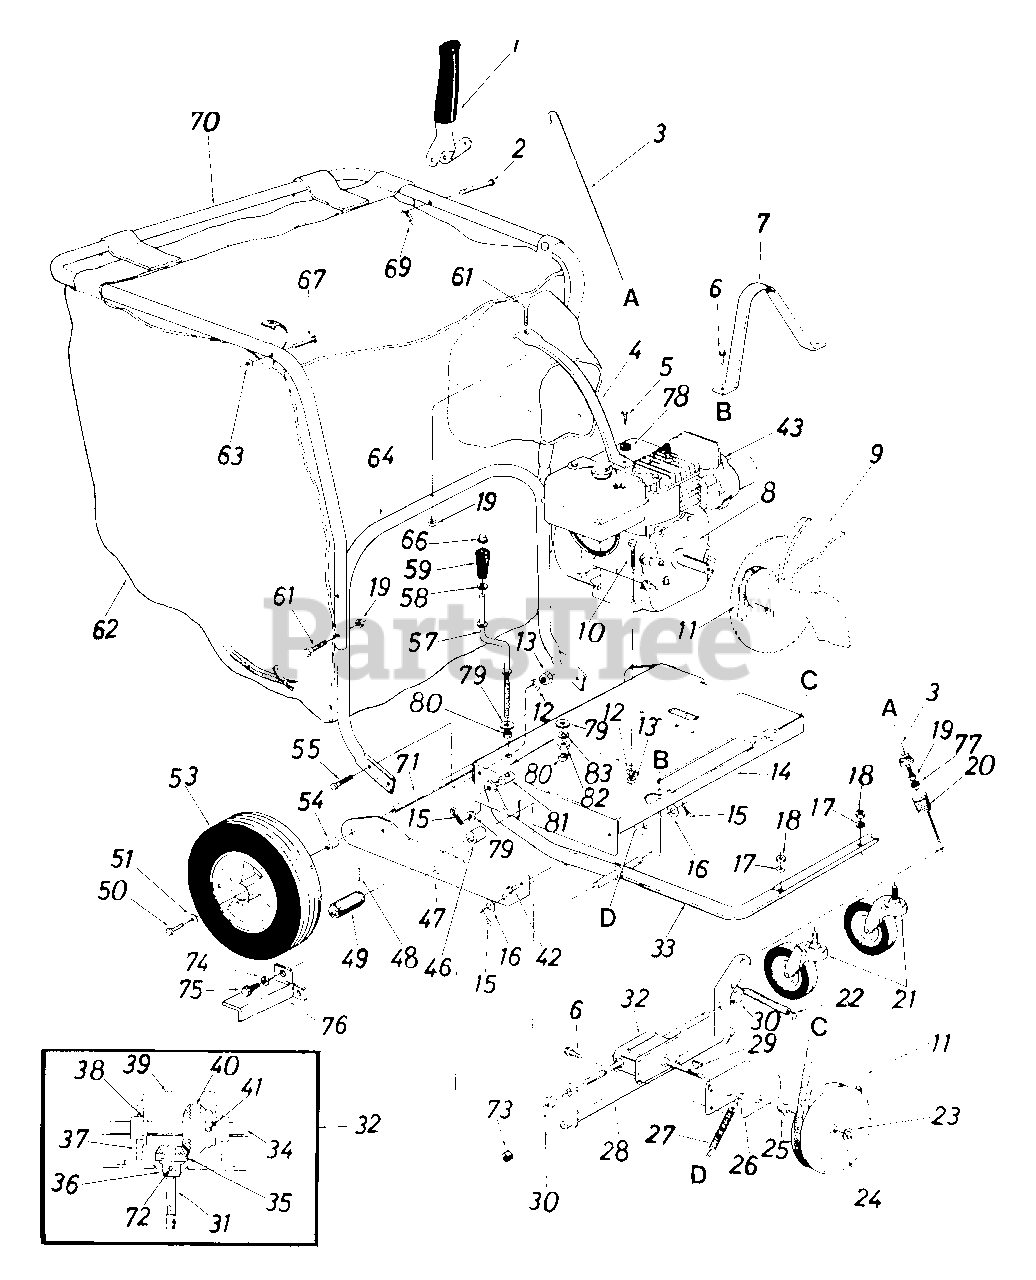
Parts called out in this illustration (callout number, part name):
1	Clutch Grip Ass'y.
2	Clevis Pin .375" Dia. x 1.88"
3	Clutch Rod 32" Lg.
4	Handle Brace (Painted)
5	Part of Engine
6	Hex Wash. Hd. AB-Tap Scr. 1/4" x .62" Lg.
9	Air Vane Plate Ass'y. (675 and 677)
11	"V"-Belts
12	L-Wash. 5/16" I.D.
13	Hex Nut 5/16-18 Thd.
16	Fl-Wash. .63" I.D. x 1.25" O.D.
17	L-Wash. 1/2" I.D.
18	Hex Nut 1/2-13 Thd.
19	Hex Cent. L-Nut 1/4-20 Thd.
20	Extension Spring .78" O.D. x .75" Lg.
21	Swivel Caster Wheel 5" Dia. x 1.25"
22	Extension Spring .38" O.D. x 7.50" Lg.
23	Snap "E"-Ring .50" Dia. Shaft
24	"V"-Pulley 5/8" x 6.50" O.D.
25	Flange Bearing .502" I.D.
28	Clutch Bracket Ass'y.
29	#2 Woodruff Key 3/32" Dia. x .81" Lg.
30	Hex Flange Bearing Bronze .625" I.D.
31	Pinion Shaft .50" Dia. x 5"
32	Gear Box Ass'y. Comp.
35	Bevel Gear .50" I.D. x 14 Teeth
36	Flange Bearing .503" I.D.
37	Gear Box
38	Flange Bearing .630" I.D.
39	Gear Box Cover
40	Bevel Gear .62" I.D. x 28 Teeth
41	Spring Pin Spiral 3/16" Dia. x 1.25" Lg.
42	Hex Wash. Hd. AB-Tap Scr. 5/16" x .75" Lg.
43	Engine
46	Spacer .63" I.D. x .88" 0 D. x 56" Lg
49	Drive Pinion
50	Hex Locking Bolt 5/16-24 x .62" Lg.
51	Fl-Wash. .34" I.D. x.87" O.D.
53	Wheel Ass'y. Comp. 12" x 3"
54	Spacer .63" I.D. x 1.0" 0 D. x .94" Lg.
55	Hex Bolt 5/16-18 x .75" Lg.
57	Height Adjustment Crank
58	Fl-Wash. .385" I.D. x .62" O.D.
59	Crank Knob
61	Hex Bolt 1/4-20 x 1.75" Lg.
62	Vacuum Bag - Felt
63	Push Speed Nut .25" Dia. Stud
66	Push Nut 3/8" Dia.
67	Stud Pin .250" Dia. x 1.75"
69	Internal Cotter Pin 3/8" Dia.
70	Upper Handle (Painted)
71	Rear Axle
72	Spring Roll Pin 5/32" Dia. x 1.121
73	Spacer .82" I.D. x 1.0" 0 D. x .305 Lg
74	L-Wash . .265" I.D.
75	Hex Self-Tap Scr. 1/4" x 3/8" Lg
78	Belleville Washer
79	Fl-Wash. .35" I.D. x.87" O.D.
80	Spacer .38" I.D. x .50" 0 D. x .18" Lg.
81	Ferrule 3/8-8 x .38" Dia.
82	Hex Nut 3/8-8 Thd.
83	L-Wash. 3/8" I.D.
14530-0498	PLATE-SIDE-RH - OLD CUB YELLOW (0498)
14530-0499	PLATE-SIDE-RH - CUB BEIGE (0499)
14530-0637	PLATE-SIDE-RH - POWDER BLACK (0637)
14530-0638	PLATE-SIDE-RH - MTD/TROY-BILT RED (0638)
16273-0498	Double Caster Arm Assembly, Black - OLD CUB YELLOW (0498)
16273-0637	Double Caster Arm Assembly, Black - POWDER BLACK (0637)
16273-0638	Double Caster Arm Assembly, Black - MTD/TROY-BILT RED (0638)
16273-0648	Double Caster Arm Assembly, Black - TECH GRAY (0648)
16273-0662	Double Caster Arm Assembly, Black - OYSTER GRAY (0662)
16273-0674	Double Caster Arm Assembly, Black - YARDMAN YELLOW (0674)
16273-0691	Double Caster Arm Assembly, Black - BLACK JACK (0691)
16273-0709	Double Caster Arm Assembly, Black - MASTERCRAFT GREEN (0709)
